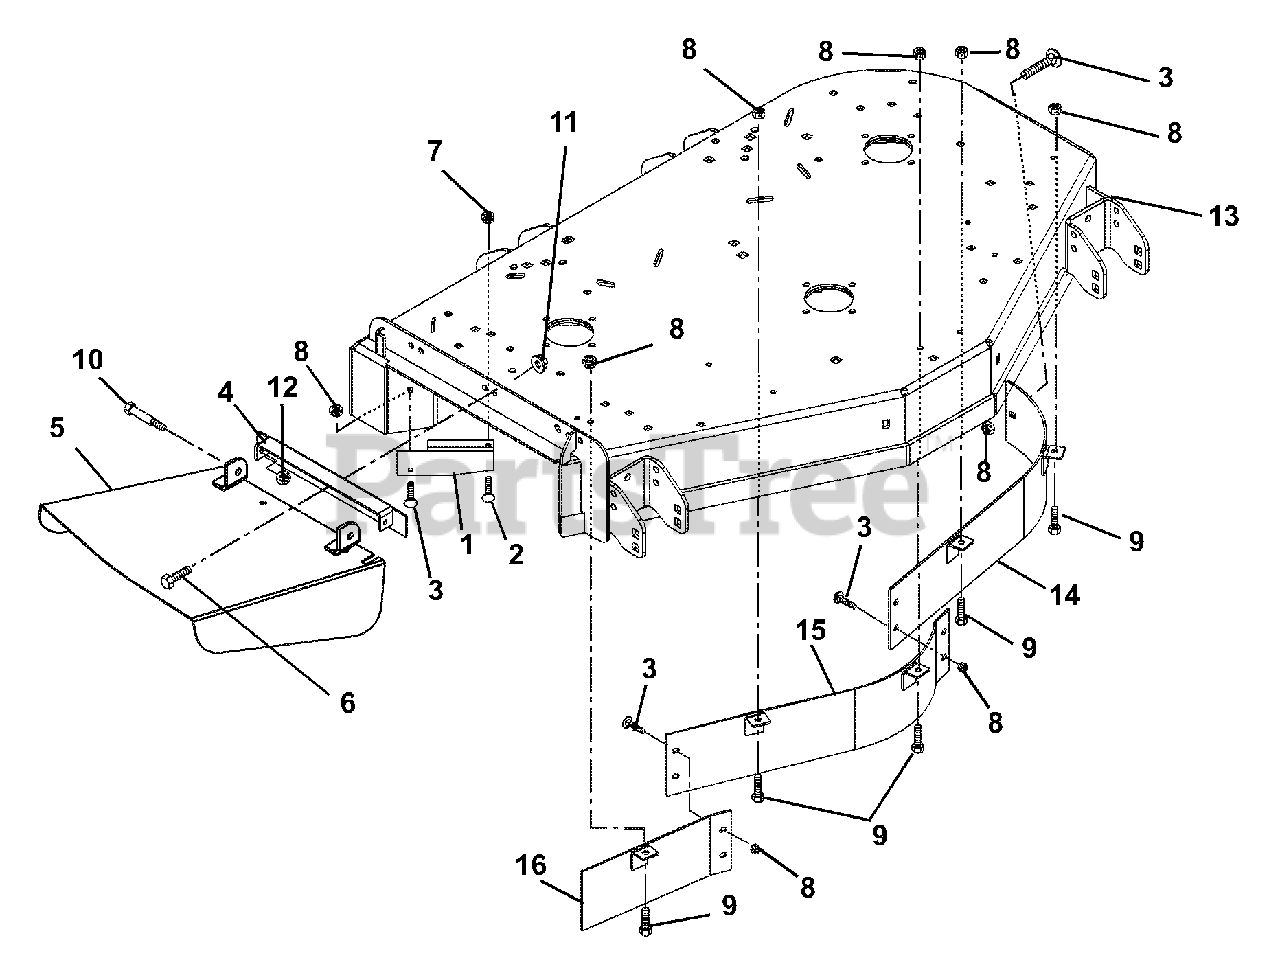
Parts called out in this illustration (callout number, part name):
1	Deflector- 60" (058, 060, 073, 075, 318, 319)
1	Deflector- 72" (059, 061, 074, 076)
2	Bolt-Round Head Square Neck .38-16 x .75 Grade 5
3	Bolt-Round Head Square Neck .31-18 x .75 Grade 5
4	Weldment, Discharge Chute Bracket
5	Chute-Discharge (058, 060, 073, 075, 318, 319)
5	Chute-Discharge (059, 061, 074, 076)
6	Bolt-Hex .38-16 x 1.00 Grade 5
7	Nut-Locking-Top-Flange .38-16
8	Nut, Locking-Top-Flange .31-18
9	Bolt, Hex .31-18 x .75 Grade 5
10	Bolt, Shoulder .38-16 x .50 Socket Head
11	Nut, Flange .375-16
12	Nut, Locking-Center .38-16
13	Weldment, 60" Mower Deck (058, 060, 073, 075, 318, 319)
13	Weldment, 72" Mower Deck- Float (059, 061,074, 076)
14	Weldment, Upper Baffle Left 60" (058, 060, 073, 075, 318, 319)
14	Weldment, Baffle, Left Front-72" (059, 061, 074, 076)
15	Weldment, Baffle, Center Front 60" (058, 060, 073, 075, 318, 319)
15	Weldment, Baffle, Center Front 72" (059, 061, 074, 076)
16	Weldment, Baffle, Right Front 60" (058, 060, 073, 075, 318, 319)
16	Weldment, Baffle, Right Front 72" (059, 061, 074, 076)
